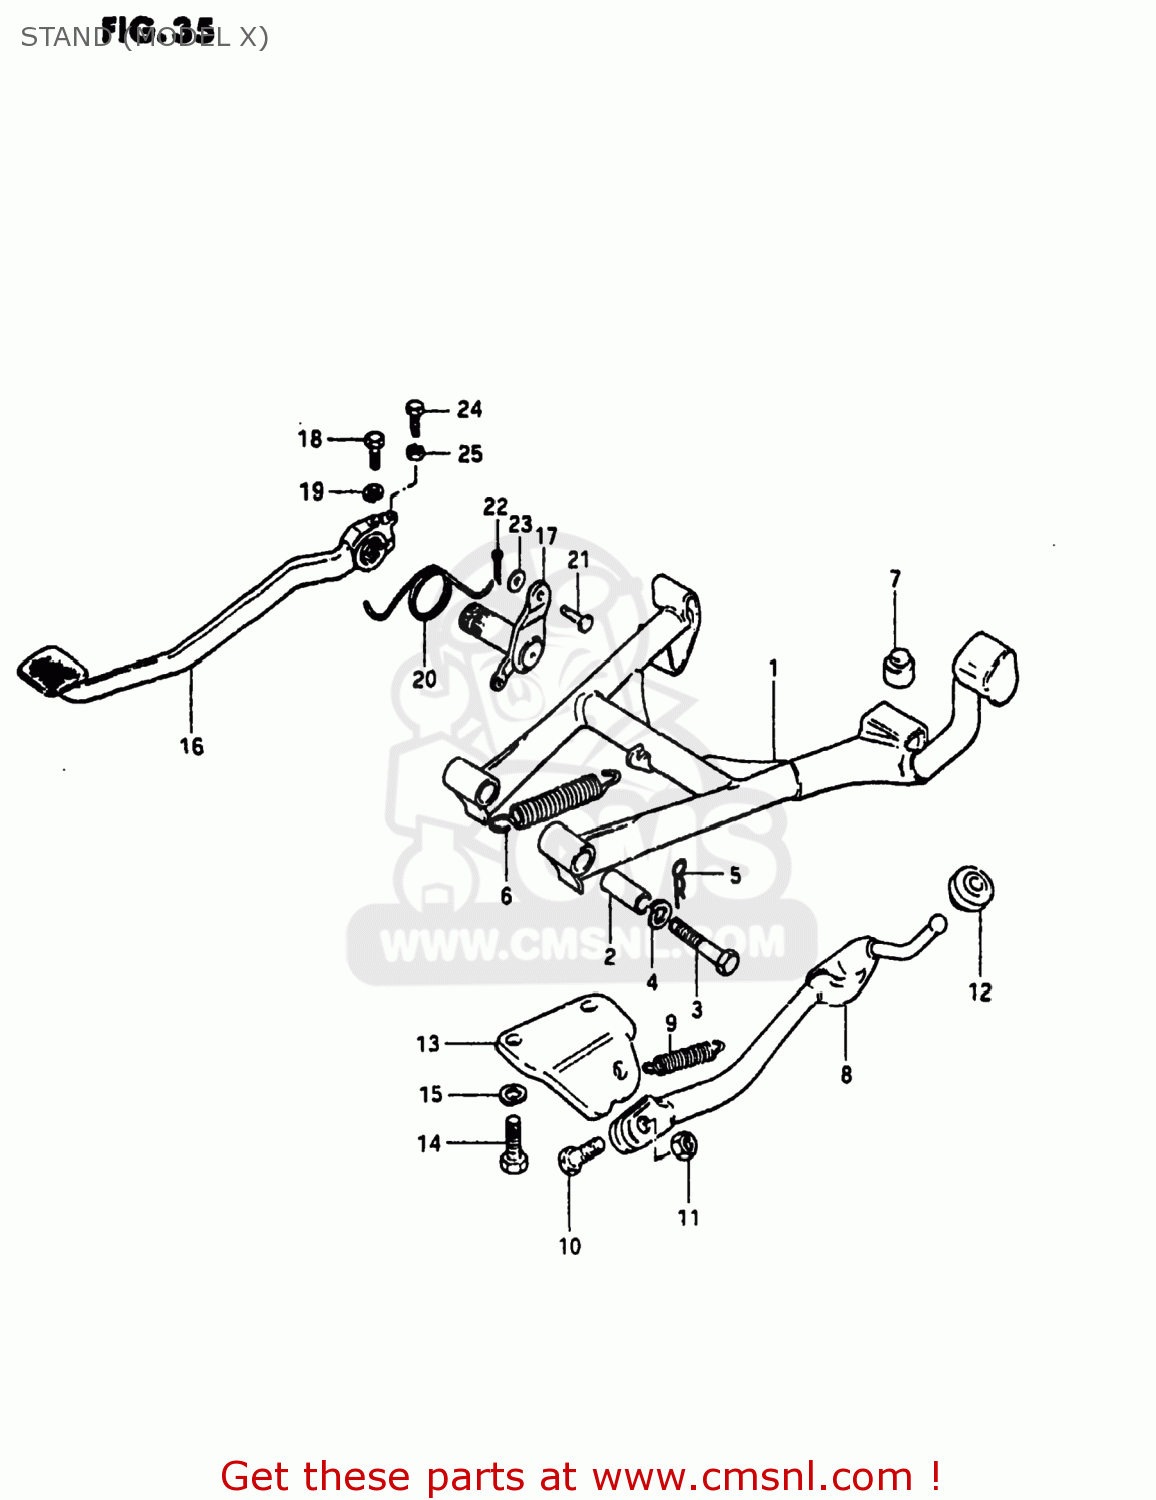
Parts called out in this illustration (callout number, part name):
1	STAND,CENTER
2	SPACER(10X16X38.8)
3	BOLT
4	LOCK WASHER
5	CLIP
6	SPRING
7	CUSHION
8	STAND,PROP
9	SPRING
10	BOLT(10X30)
11	NUTM10X1.25X8
12	CUSHION
13	BRACKET,SIDE STAND
14	BOLT
15	LOCK WASHER
16	PEDAL,BRAKE
17	ARM,BRAKE PEDAL ROD
18	BOLT (8X30)
19	LOCK WASHER
20	SPRING
21	PIN
22	PIN
23	WASHER
24	BOLT
25	NUT
